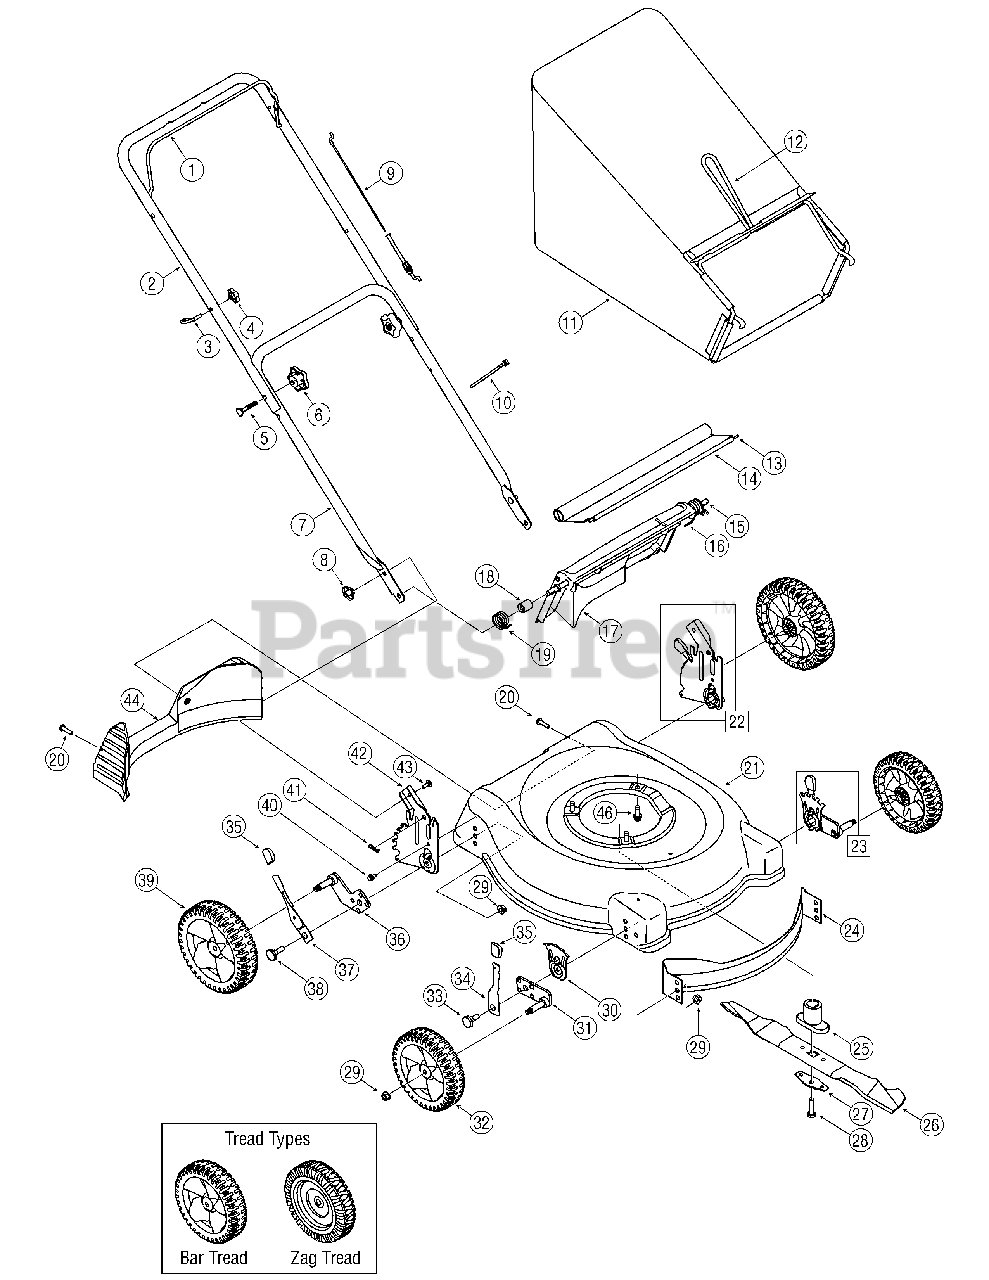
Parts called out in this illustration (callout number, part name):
3	Rope Guide
4	Wing Nut, 1/4-20
5	Carriage Bolt, 5/16-18 x 2
6	Hand Star Knob
8	Wing Nut, 1/4-20
9	Control Cable - 37.25"
9	Control Cable - 40"
9	Control Cable - 40.5"
9	Control Cable - 53"
10	Cable Tie
11	Grass Bag Assembly
13	Trailshield Wire
14	Trailshield
15	Rear Door Pivot Rod
16	Torsion Spring LH
17	Rear Discharge Door
18	Spacer
19	Torsion Spring RH
20	Screw, 1/4-15 x 1.25
22	Handle Bracket Assy - RH
22	Handle Bracket Assy - LH
23	Height. Adj. Assy. Front - LH
23	Height Adj. Assy. Front - RH
24	Front Baffle
25	Blade Adapter
26	Blade
27	Blade Bell Support
28	Screw, 3/8-24 x 2.50
29	Flange Lock Nut, 3/8-16
30	Height Adjustment Plate
31	Pivot Arm Assembly - RH
31	Pivot Arm Assembly - LH
32	Front Wheel - 7 x 1.8 Spoke Gray, Bar Tread w/o bearing
33	Shoulder Screw
34	Spring Lever
35	Height Adjustment Knob
36	Pivot Arm Assembly - RH
36	Pivot Arm Assembly - LH
37	Spring Lever
38	Shoulder Screw
39	Rear Wheel - 8 x 1.8 Slot Hub Gray, Bar Tread w/o bearing
39	Rear Wheel - 8 x 1.8 Spoke Gray, Bar Tread w/o bearing
39	Rear Wheels - 8 x 2 Zag Tread w/o bearings
39	Rear Wheels - 8 x 2 Disc Hub Zag Tread w/ BB
39	Ball, Bearings for 734-2004A wheel
40	Screw, 1/4-20 x .625
41	Hairpin Clip
42	Rear Handle Bracket - RH
42	Rear Handle Bracket - LH
43	Carriage Bolt, 1/4-20
44	Rear Baffle
